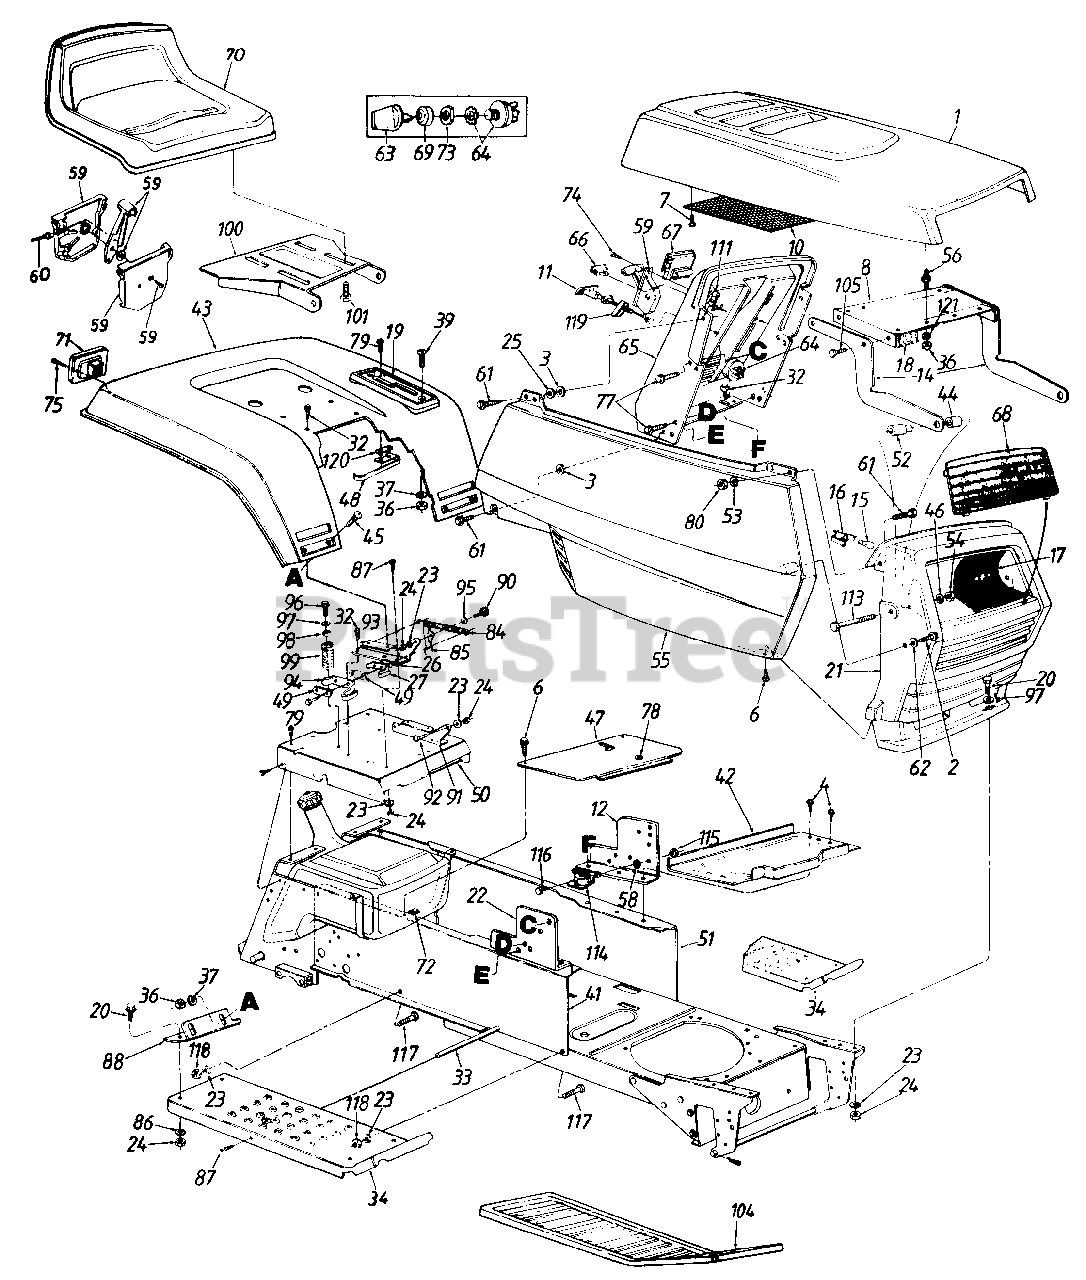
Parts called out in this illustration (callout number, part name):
3	Bolt Retainer 1/4" I.D.
4	Hex AB-Tap Scr. 1/4 x .62" Lg.
6	Truss Mach. B-Tap Scr. #10 x .5" Lg.
7	Hex Wash Hd. AB-Tap Scr. #8 x .5" Lg.
8	Hood Plate
11	Choke Control
12	Dash Support Brkt. - L.H.
14	Hood Hinge
15	Lamp
16	Twist Lock - Lamp Socket
17	Reflector - Headlight
19	Speed Control Index Brkt.
20	Hex Bolt 5/16-18 x 1.0" Lg.
21	Grille
22	Dash Support Bracket - R.H.
23	L-Wash. 5/16" I.D.
24	Hex Nut 5/16-18 Thd.
25	Fl-Wash. 1/4" I.D. x .93" O.D.
26	Insulator Boss Plate
27	Seat Spring Switch
32	Hex Wash. Hd. AB-Tap Scr. 5/16 x .75" Lg.
33	Running Board Rod
37	L-Wash. 1/4" I.D.
39	Truss Mach. Scr. 1/4-20 x 1.0" Lg.
41	R.H. Side Frame
42	Battery Plate
45	Carriage Bolt 1/4-20 x .50" Lg.
46	Fl-Wash. .328" I.D. x .68" O.D.
47	Transmission Panel
48	Reverse Safety Switch
49	Insulator Plate
53	Fl-Wash. .281" I.D. x .5" O.D.
54	Hex Cent. L-Nut 5/16-18 Thd.
55	Side Cover Ass'y. - R.H.
56	Double Ended Stud 1/4-20 Thd.
58	Ext. L-Wash. 1/4" I.D.
59	Throttle Control Box Ass'y.
60	Throttle Control Wire 35" Lg.
61	Hex Bolt 1/4-20 x .62" Lg.
62	Fl-Wash. .281" I.D. x .73" O.D.
64	Ignition Switch
65	Dash Panel
66	Light Switch
67	Ammeter
68	Lens
69	Ignition Switch Cap
71	Taillight Ass'y.
72	Speed Nut #10Z
73	Ignition Switch Nut
74	Truss Mach. AB-Tap Scr. #10 x .5" Lg.
75	Truss Hd. AB-Tap Scr. #6 x .62" Lg.
77	Hex Wash. Hd. Tap Scr. 1/4 x .75" Lg.
78	Snap Bushing
79	Hex Wash. Hd. AB-Tap Scr. #8 x .50" Lg.
80	Hex L-Nut 1/4-20 Thd.
84	Ext. Spring 5.31" Lg.
85	Seat Lift Brkt.
86	Bell-Wash. .345" I.D. x .88" O.D.
87	Truss Machine Scr. 5/16-18 x .75" Lg.
95	Spr.-Wash. .445" I.D.
96	Hex Wash. Hd. Tap Scr. 5/16-18 x .75" Lg.
97	Fl-Wash. .344" I.D. x 1" O.D.
99	Compression Spring
100	Seat Pivot Bracket
101	Hex Tap Scr. 3/8-16 x .75"
105	Hex Tap Scr. 1/4-20 x .5" Lg.
111	Speed Nut 1/4-20 Thd.
113	Hex Bolt 5/16-18 x 2.75"
114	Solenoid
115	Hex Sems Nut 1/4-20 Thd.
116	Hex Bolt 1/4-20 x .5" Lg.
117	Rib Neck Bolt 5/16-24 x .75" Lg.
118	Hex Nut 5/16-24 Thd.
119	Retainer Clip
120	Insulator Nut Plate
121	Bell-Wash. .265" I.D. x .75" O.D.
